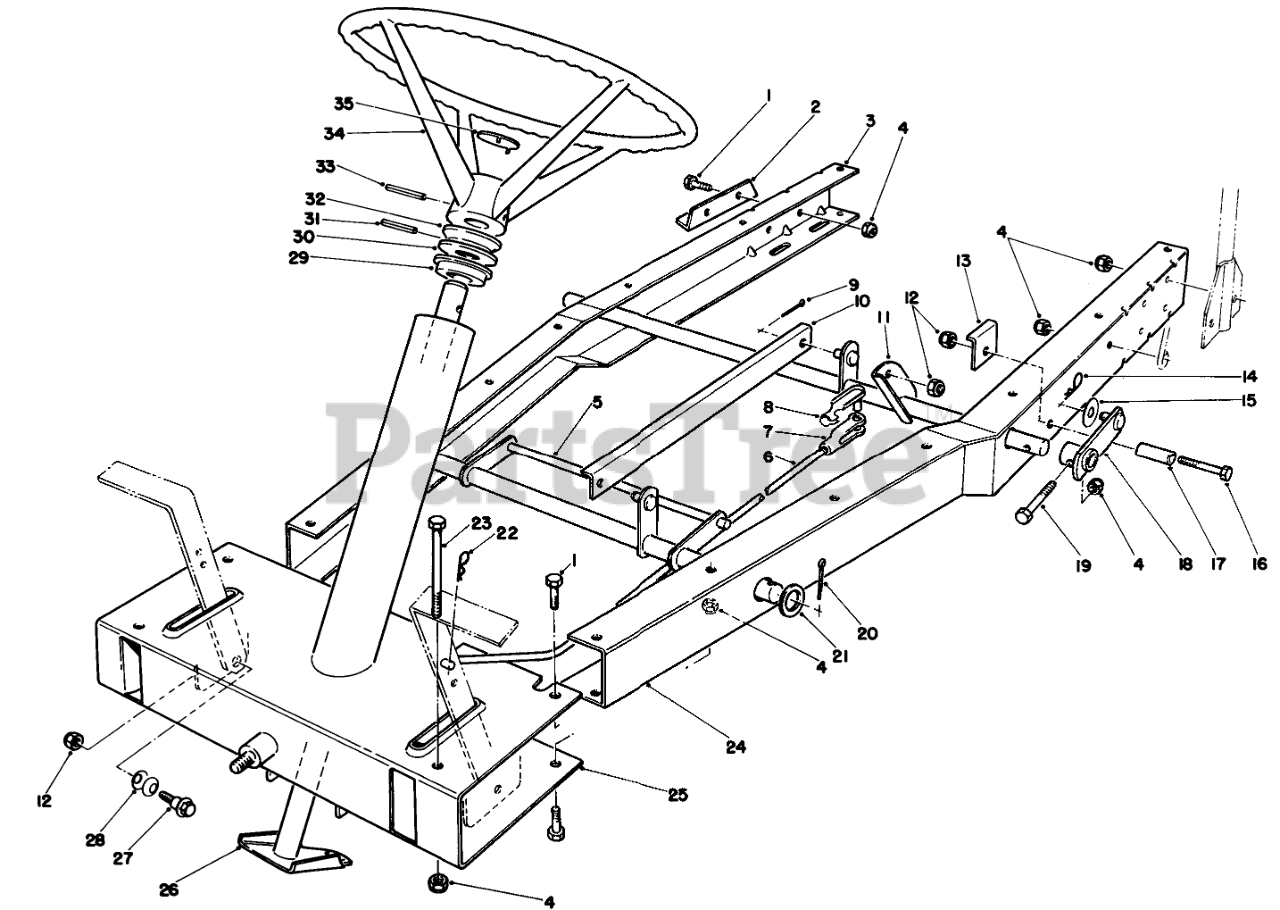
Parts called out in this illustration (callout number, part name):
1	SCREW-HH
2	Mount-Axle Brg.
3	Channel-R.H.
4	NUT-LOCK, NI
5	Deck Lift W.A.-Front
6	ROD-CLUTCH
7	CLEVIS-ADJ
8	CLEVIS PIN ASM
9	PIN-COTTER
10	Bracket-Hoc Link
11	Tube W.A.-Rear Support
12	NUT-LOCK, NI
13	Brace-Deck Stop
14	PIN-HAIR
15	WASHER
16	SCREW-HH
17	SPACER-STOP,DECK
18	Lever W.A.-Hoc
19	Bolt
20	PIN-COTTER
21	WASHER-FLAT
22	PIN-COTTER
23	SCREW-HH
24	Channel-L.H.
25	Frame W.A.-Front
26	Shaft W.A.-Steering
27	BOLT-SHOULDER
28	WASHER-BELLEVILLE
29	BUSHING-STEERING
30	WASHER-STEERING
31	PIN-ROLL
32	SPACER-STEERING
33	PIN-ROLL
34	STEERING WHEEL ASM
35	STEERING WHEEL INSERT
